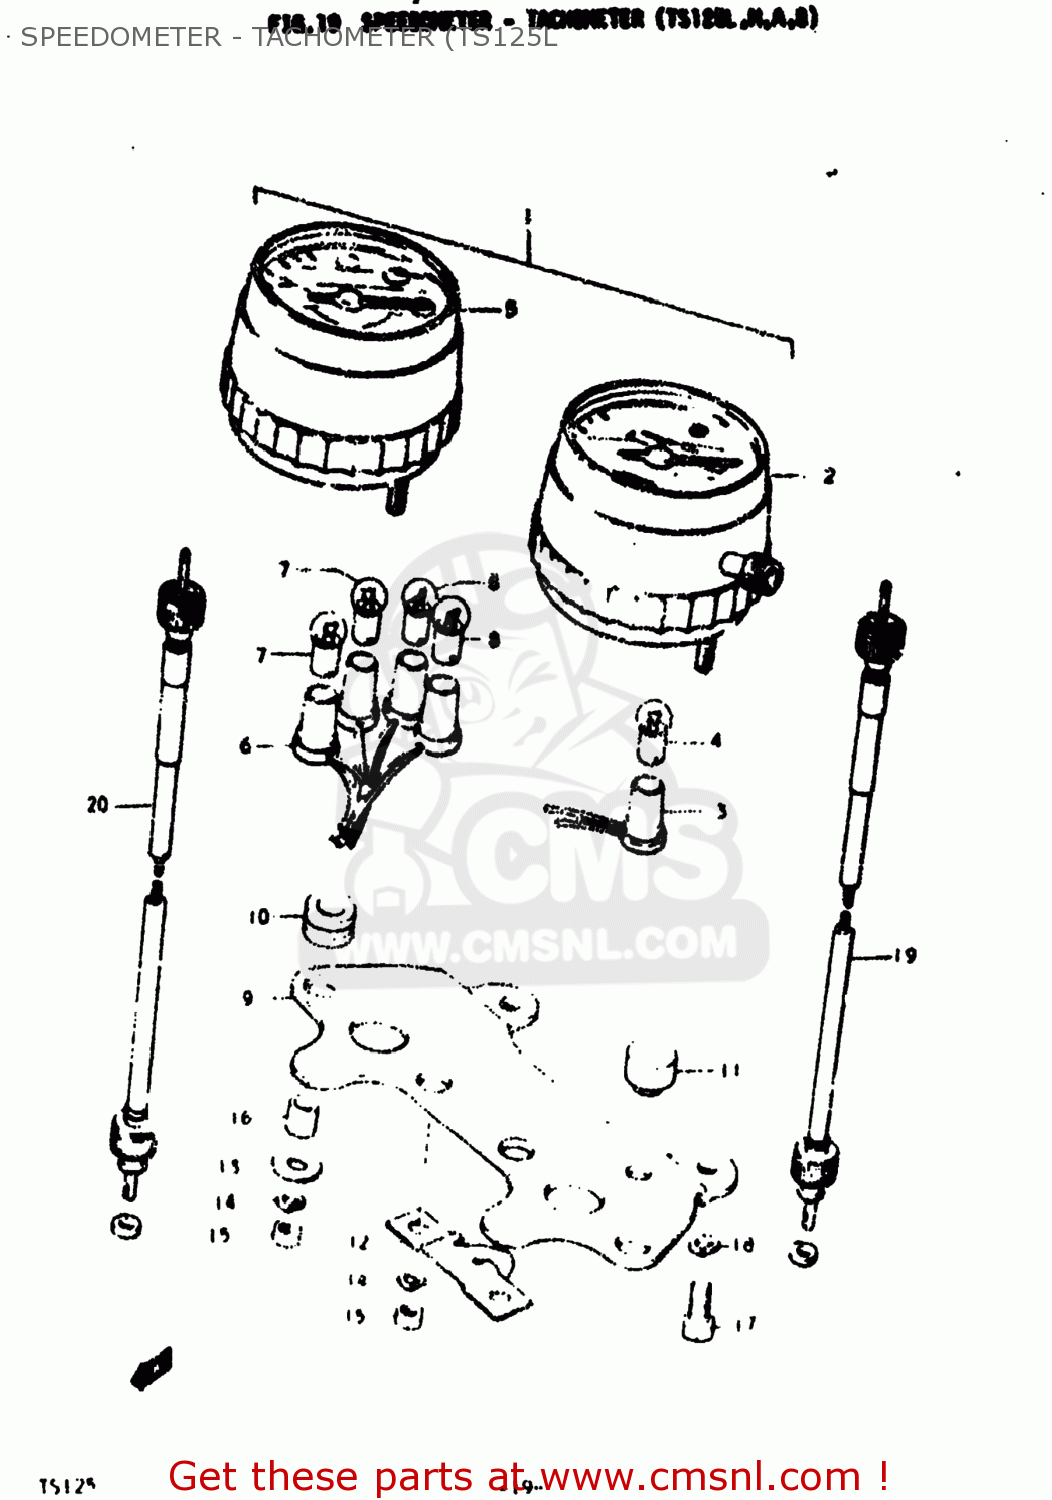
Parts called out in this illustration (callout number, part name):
1	SPEEDOMETER ASSEMBLY
2	SPEEDOMETER ASSEMBLY
3	SOCKET,METER
4	BULB(6V/3W)
5	METER,TACHOMETER
6	SOCKET,TACHOMETER
7	BULB(6V/3W)
8	BULB(6V1.7W,STANLEY,A61A)
9	BRACKET,METER
10	CUSHION
11	CUSHION,METER
12	COVER,METER,UNDER
13	WASHER (5.5X16X1.2)
14	LOCK WASHER
15	NUT
16	SPACER,METER NO.2
17	BOLT
18	LOCK WASHER
19	CABLE ASSY,SPEEDOMETER
20	CABLE ASSY,TACHOMETER
